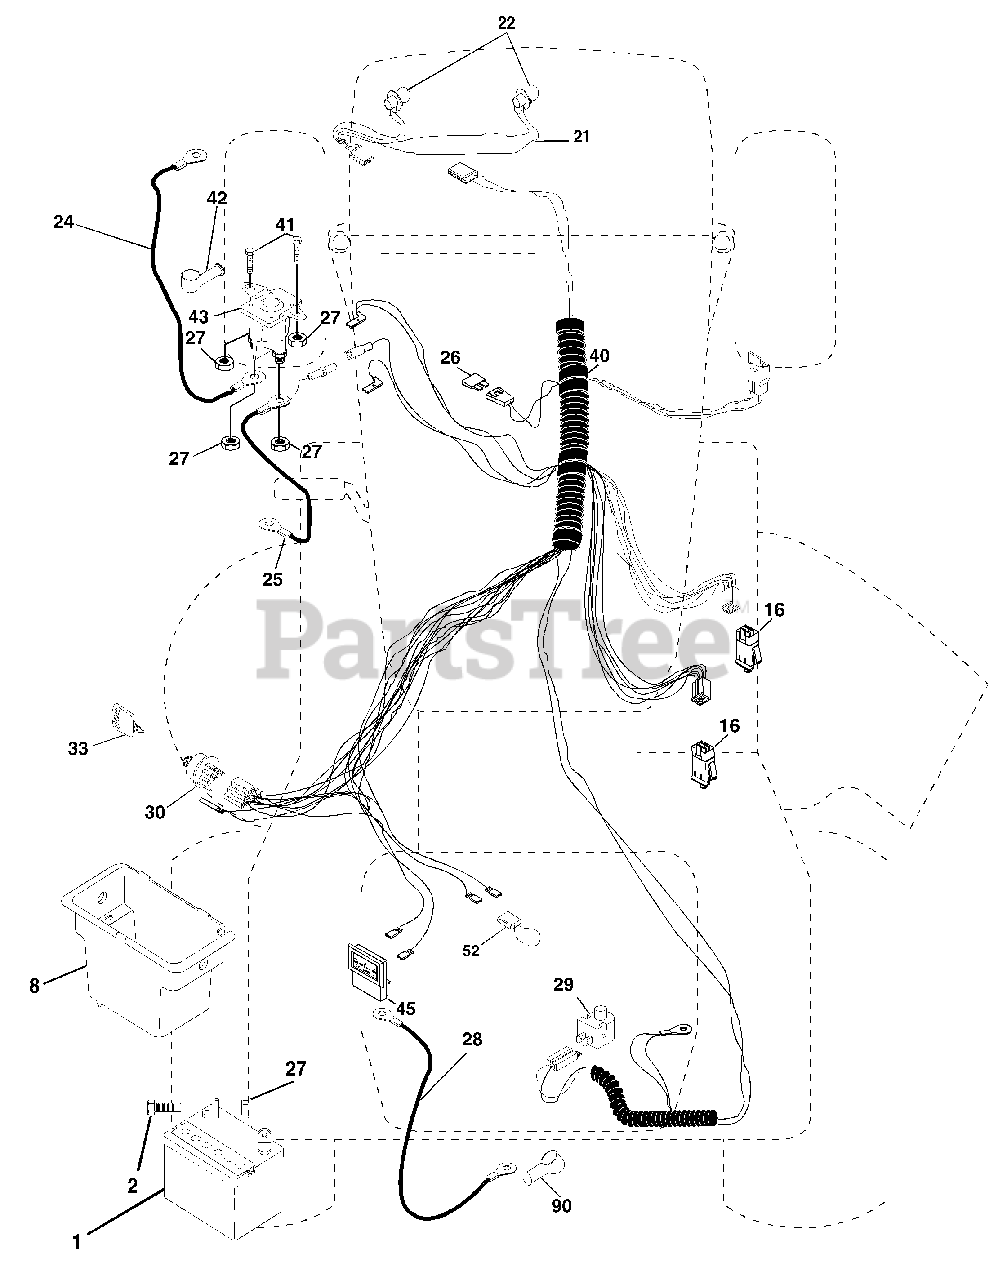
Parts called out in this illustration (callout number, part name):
1	Battery
2	Bolt Hex Hd 1/4-20unc X 3/4
8	Battery Box
16	Switch Interlock Push-In
21	Harness Socket Light
22	Bulb, Light # 1156
24	Cable Battery
25	Cable Battery 6 Ga Red w/16 wire
26	Fuse
27	Nut Keps Hex 1/4-20 Unc
28	Cable Ground 6ga 12 black
29	Switch Plunger Nc Gray
30	Switch Ign
33	Key Ign Molded Generic
40	Harness Ign
41	Bolt Fin Hex 1/4-20unc x 1/2
42	Cover Terminal Red
43	Solenoid
45	Ammeter Rectangular
52	Protection Loop
90	Cover Terminal
